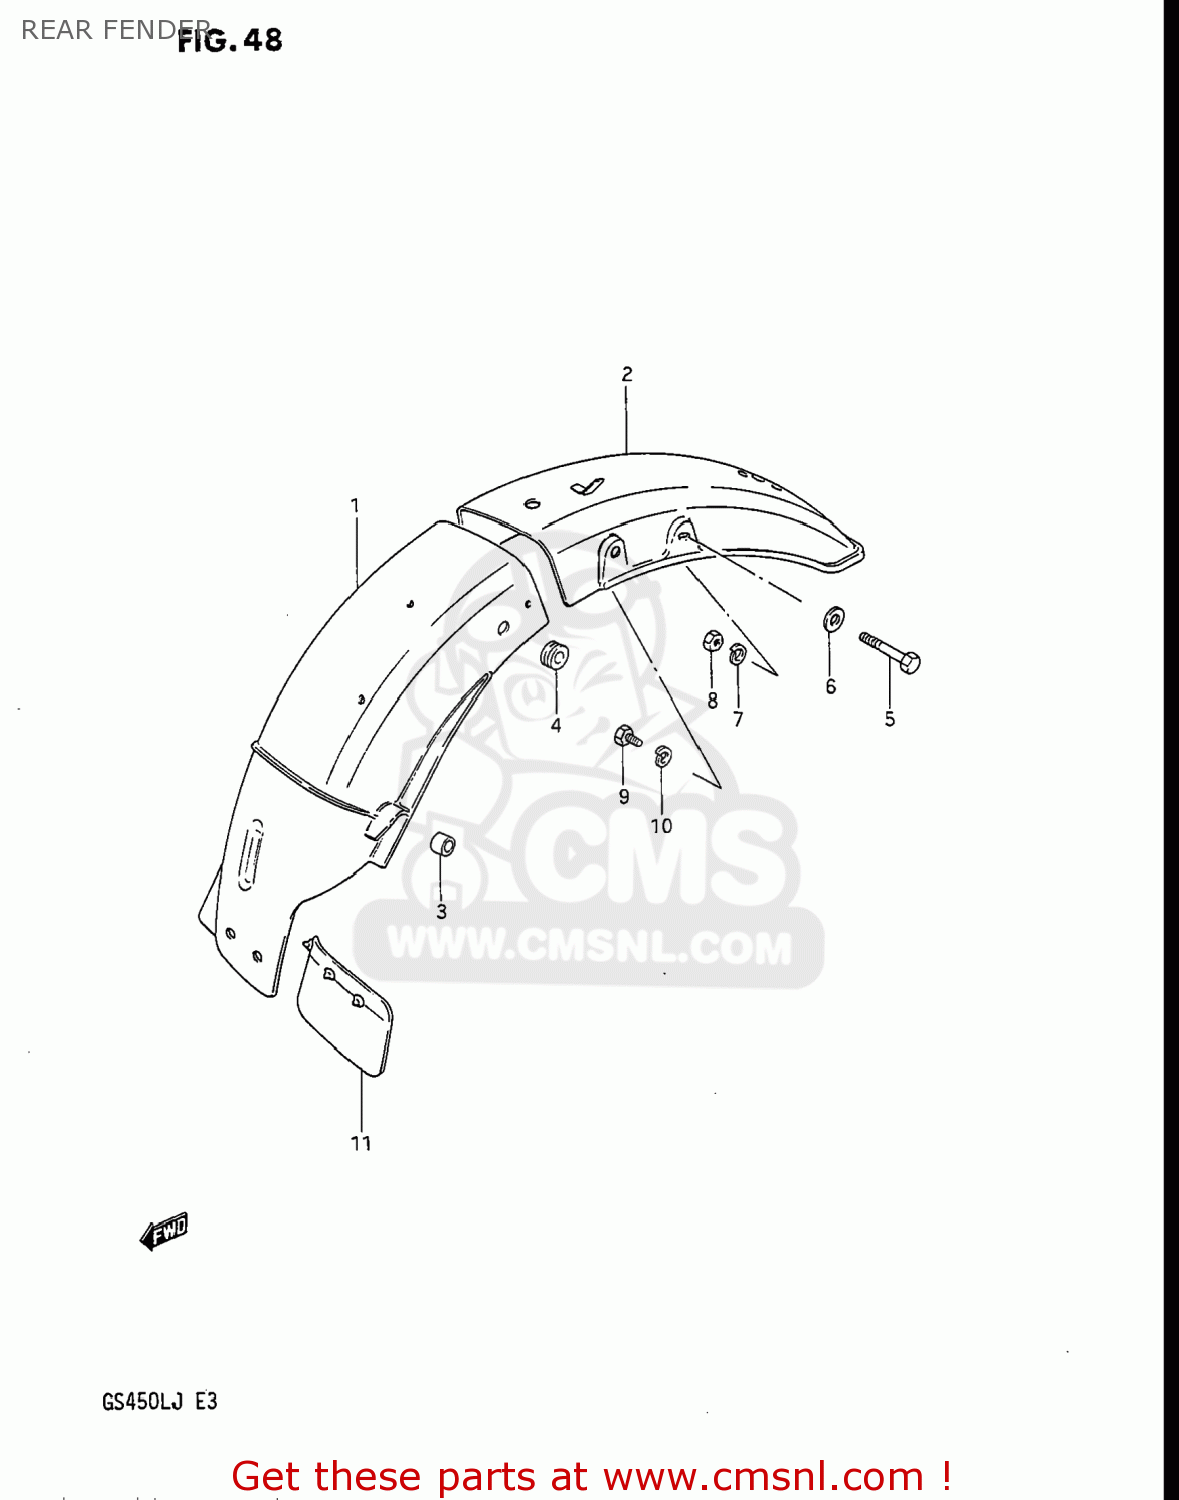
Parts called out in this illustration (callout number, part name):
1	FENDER,REAR
2	FENDER,REAR
3	CUSHION
4	CUSHION
5	BOLT
6	WASHER
7	LOCK WASHER
8	NUT
9	BOLT,8X16
10	LOCK WASHER
11	GUIDE,RR FENDER MUD
